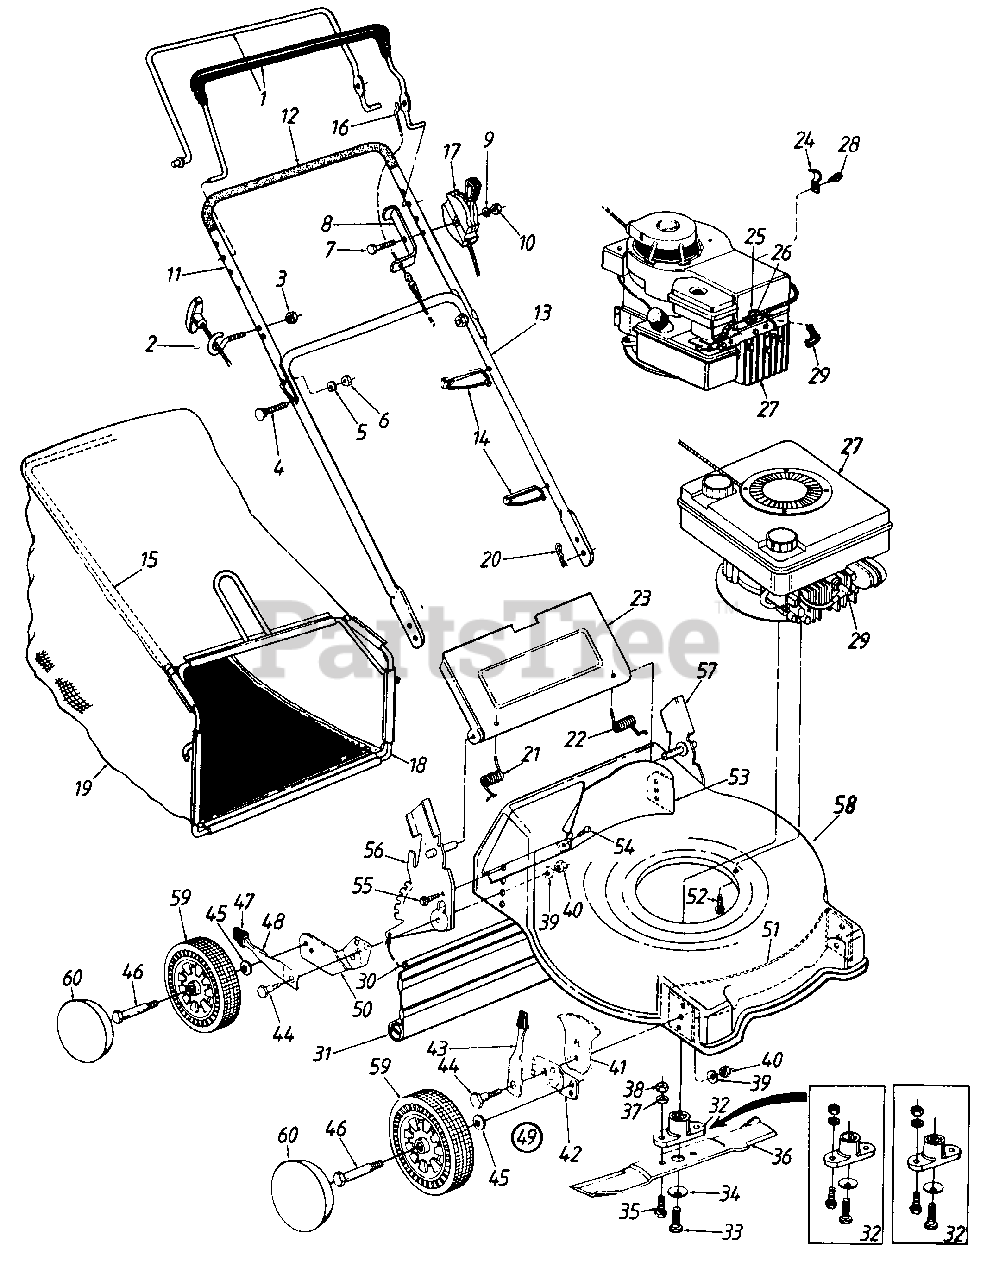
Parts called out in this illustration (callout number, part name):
1	Control Handle Ass'y.
2	Rope Guide Bolt
3	Hex L-Nut 1/4-20 Thd.
4	Curved Carr. Bolt 5/16-18 x 1.38" Lg.
5	L-Wash. 5/16" I.D.
6	Hex Nut 5/16-18 Thd.
7	Hex Bolt 1/4-20 x 1-7/8" Lg.
8	Cable Brkt.
9	Spr. Wash. 1/4" I.D.
10	Hex Nut 1/4-20 Thd.
11	Upper Handle
12	Foam Grip
13	Lower Handle
14	Cable Tie
16	Control Cable-36"
17	Throttle Control Ass'y. Comp.
20	Int. Cotter Pin 5/16" Dia.
21	Door Spring-R.H.
22	Door Spring-L.H.
25	Cable Clamp
26	Hex AB-Tap Scr. #8 x .5" Lg.
27	Engine
28	Hex B-Tap Scr. #10 x .38" Lg.
29	Spark Plug Boot
30	Wire Rod
31	Rear Flap
32	Blade Adapter Kit (Keyed)
33	Hex Bolt 3/8-24 x 1.5" Lg.
34	Bell-Wash..39" I.D.
35	Hex Bolt 3/8-24 x 1" Lg.
36	21" Blade
37	L-Wash. 3/8" I.D.
38	Hex Nut 3/8-24 Thd.
39	Bell-Wash. .39" I.D. x 1.38"
40	Hex Nut 3/8-16 Thd.
41	Height Adj. Plate
43	Spring Lever Ass'y. w/Knob
44	Shld. Bolt .5" Dia. x 357"
45	Bell-Wash. .38" I.D. x .88" O.D.
46	Axle Bolt
47	Spring Lever Knob
48	Spring Lever
49	Height Adj. Ass'y. Comp.-R.H.
50	Pivot Bar
54	Torx Bolt 1/4-20 x .5" Lg.
55	Hex L-Wash. Hd. AB-Tap Scr. 1/4 x .62" Lg.
56	Handle Brkt. Ass'y.-R.H.
57	Handle Brkt. Ass'y.-L.H.
60	Hub Cap
